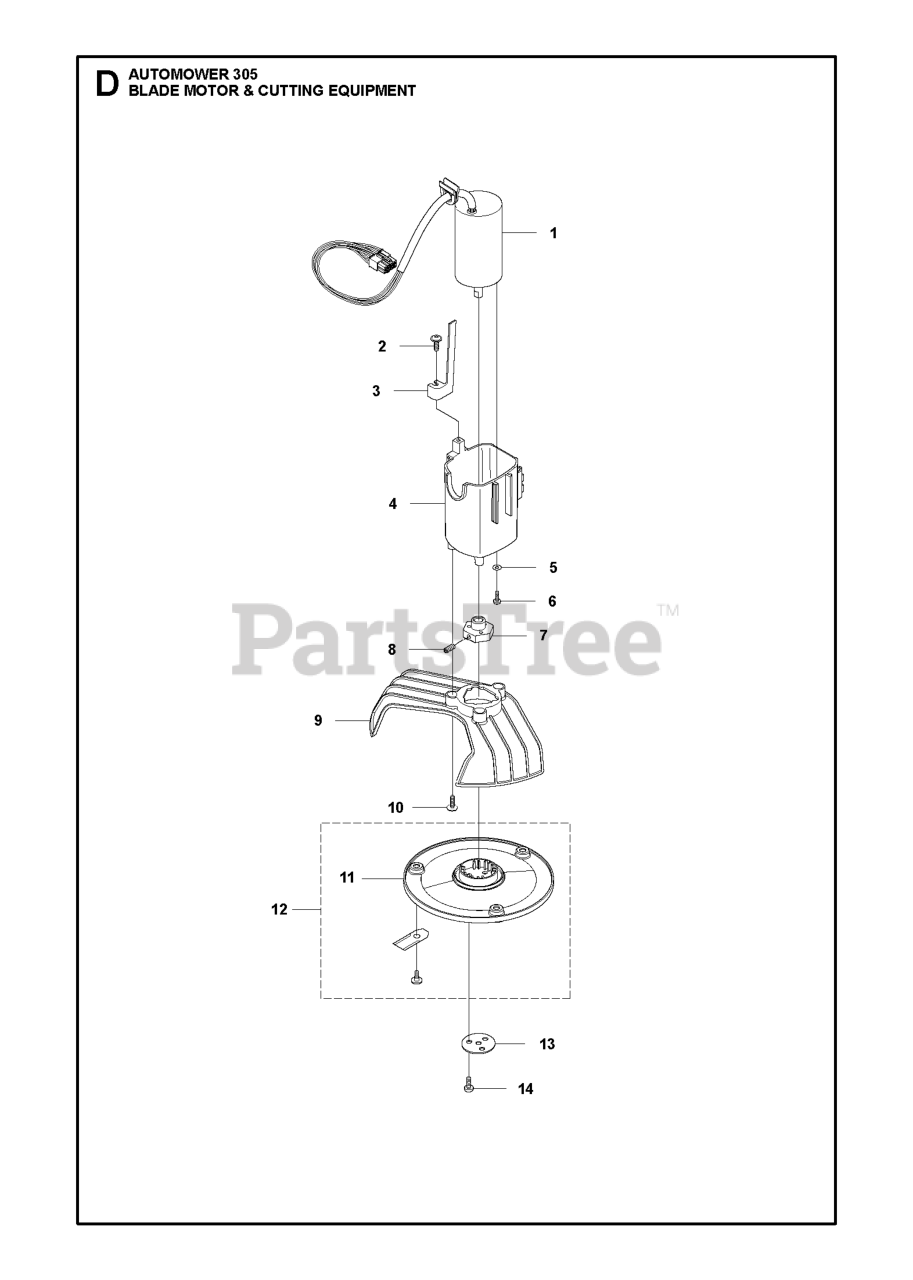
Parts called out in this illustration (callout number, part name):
2	SCREW 14MM
3	HEIGHT INDICATOR
7	HUB CUTTING MOTOR
8	SCREW IHSETM M5X10 8.8 ZP-BC
10	SCREW 14MM
11	CUTTING DISC
13	WASHER DRIVE WHEEL
14	SCREW ITXPANM M4X12 A2-70 PAT
